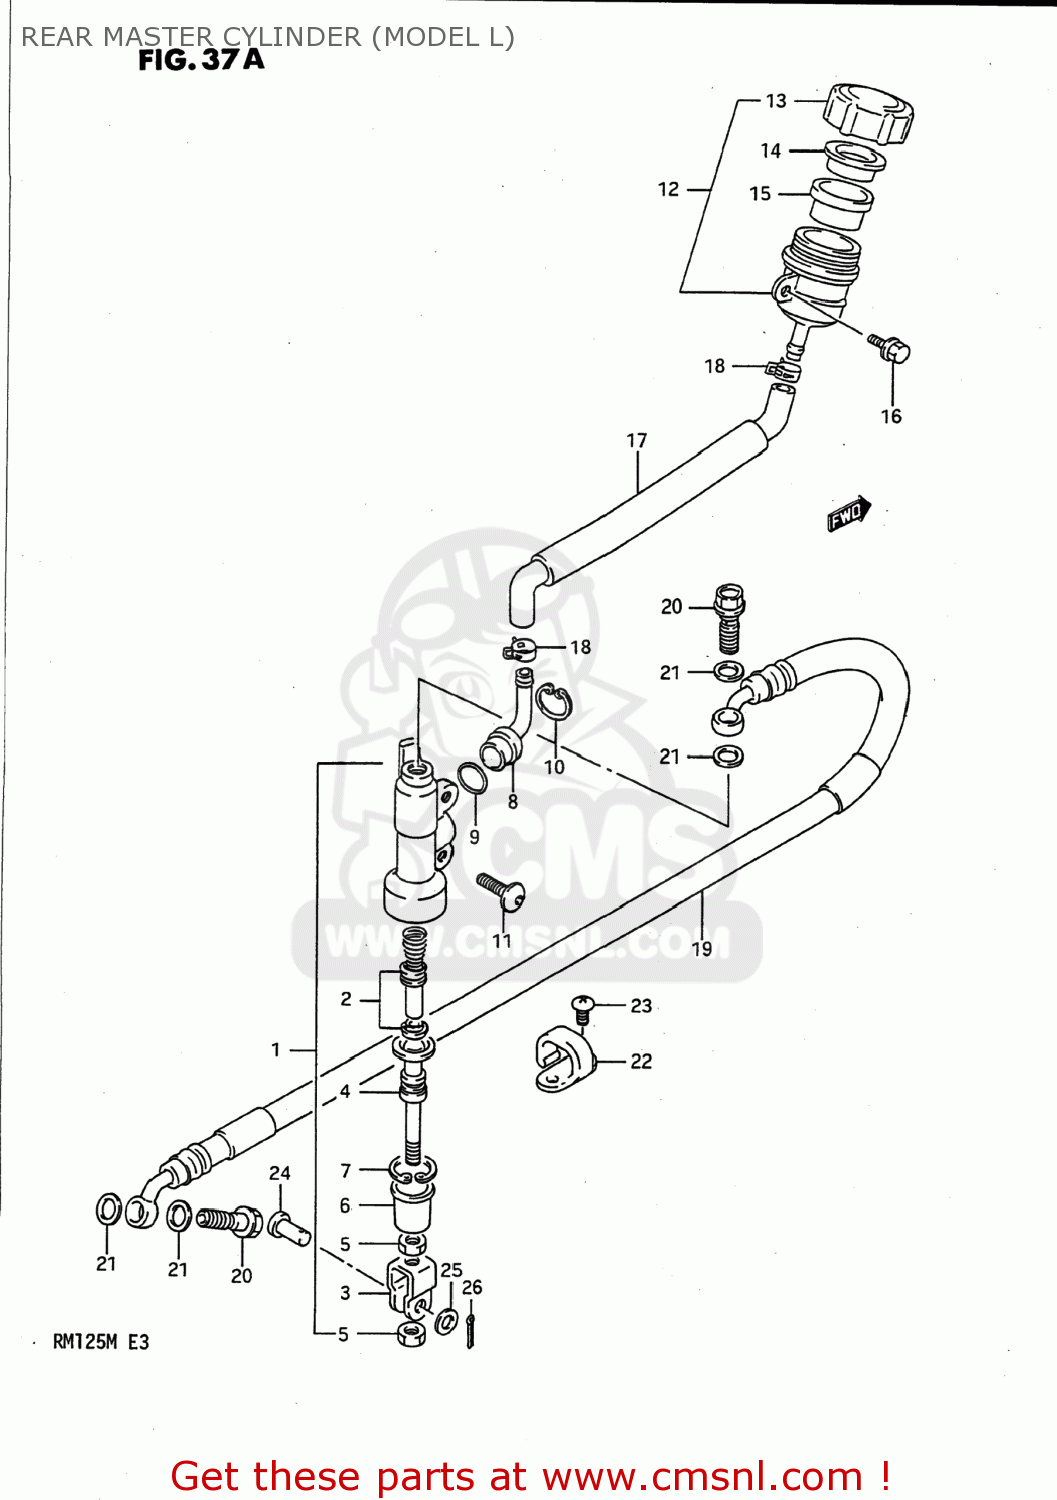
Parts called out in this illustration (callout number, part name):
1	CYLINDER ASSEMBLY,REAR MASTER
2	PISTON/CUP SET
3	YOKE
4	ROD,PUSH
5	NUT
6	BOOT
7	CIRCLIP
8	CONNECTOR
9	O RING
10	CIRCLIP
11	SCREW(6X16)
12	TANK ASSY,RESERVOIR
13	CAP
14	PLATE
15	DIAPHRAGM
16	BOLT
17	HOSE,RESERVOIR
18	CLAMP,RESERVOIR HOSE
19	HOSE,REAR BRAKE
20	BOLT UNION
21	WASHER(10X15X1.5)
22	GUIDE,RR BRAKE HOSE
23	SCREW(5X10)
24	PIN(8X20)
25	WASHER(8.5X13X1.6)
26	PIN
